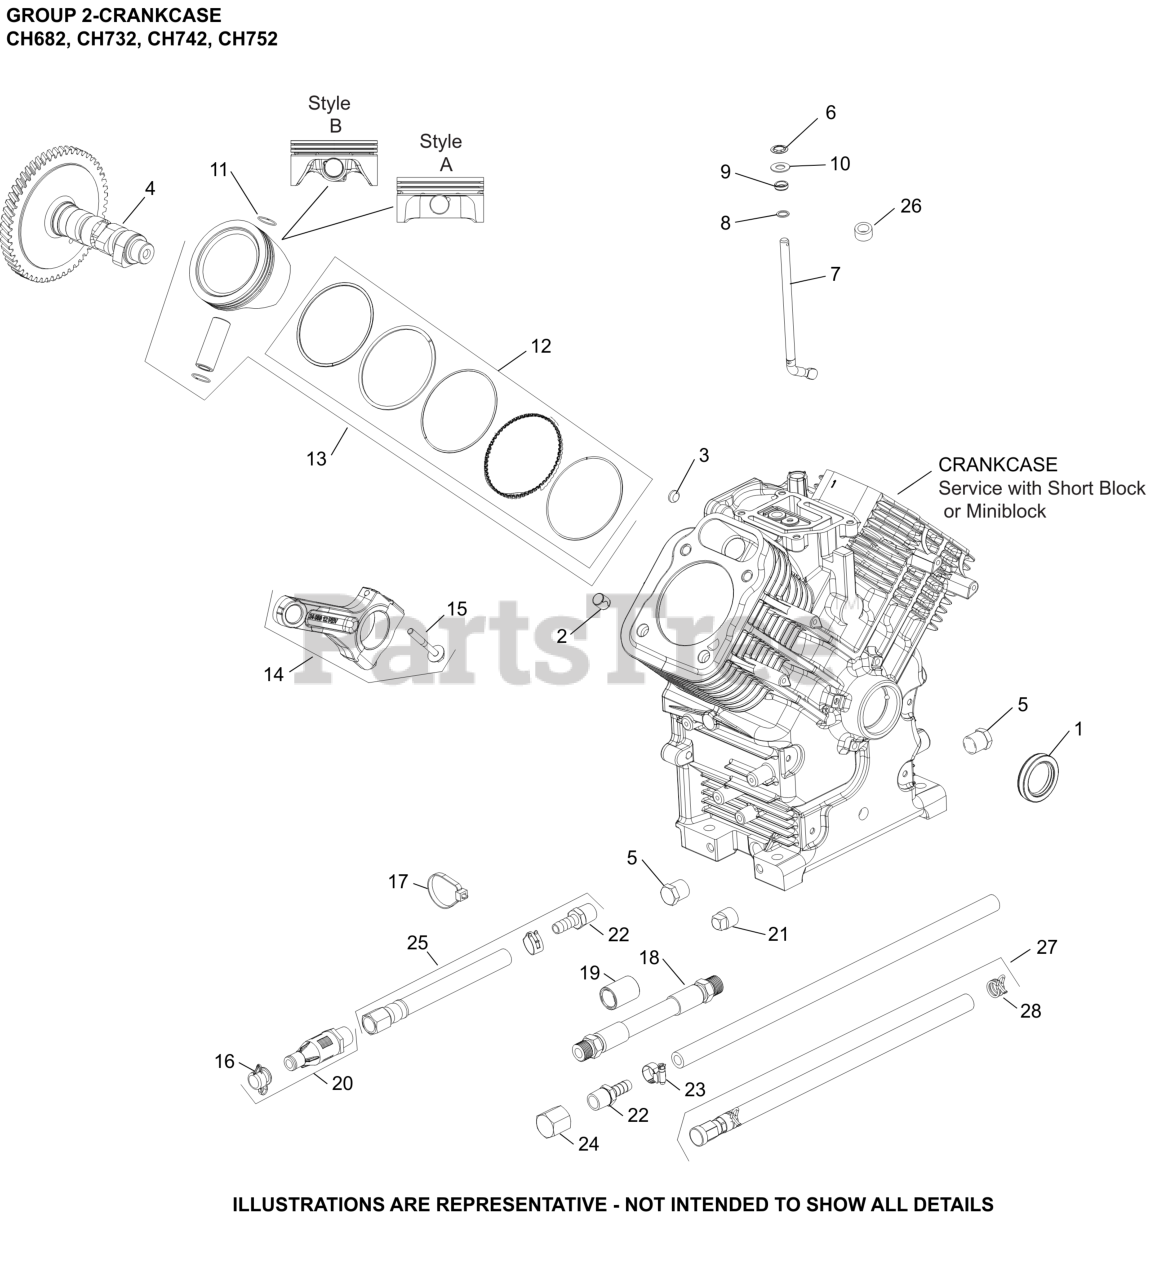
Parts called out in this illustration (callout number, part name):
1	SEAL, OIL (HELIX LIP)
2	PIN, LOCATING
3	PLUG, CUP
4	KIT, CAMSHAFT
5	PLUG, HD PIPE 3/8"
6	RETAINER, RING
8	WASHER, FLAT 11/32"
9	SEAL, GOVERNOR CROSS SHAFT
10	WASHER, FLAT 9 MM
11	RETAINER, PISTON PIN
13	KIT, PINNED PSTN/RING SET (STD)
13	KIT, PINNED PSTN/RING SET (.08)
14	ROD, ASSEMBLY CONNECTING
15	KIT, ROD BOLTS-(#25086677S)
NI	SHAFT, GOVERNOR CROSS
NI	RING, SET (STD) PINNED
NI	RING, SET (.08) PINNED
NI	RING, SET (.25) PINNED
NI	RING, SET (.50) PINNED
NI	KIT, PINNED PSTN/RING SET (.25)
NI	KIT, PINNED PSTN/RING SET (.50)
